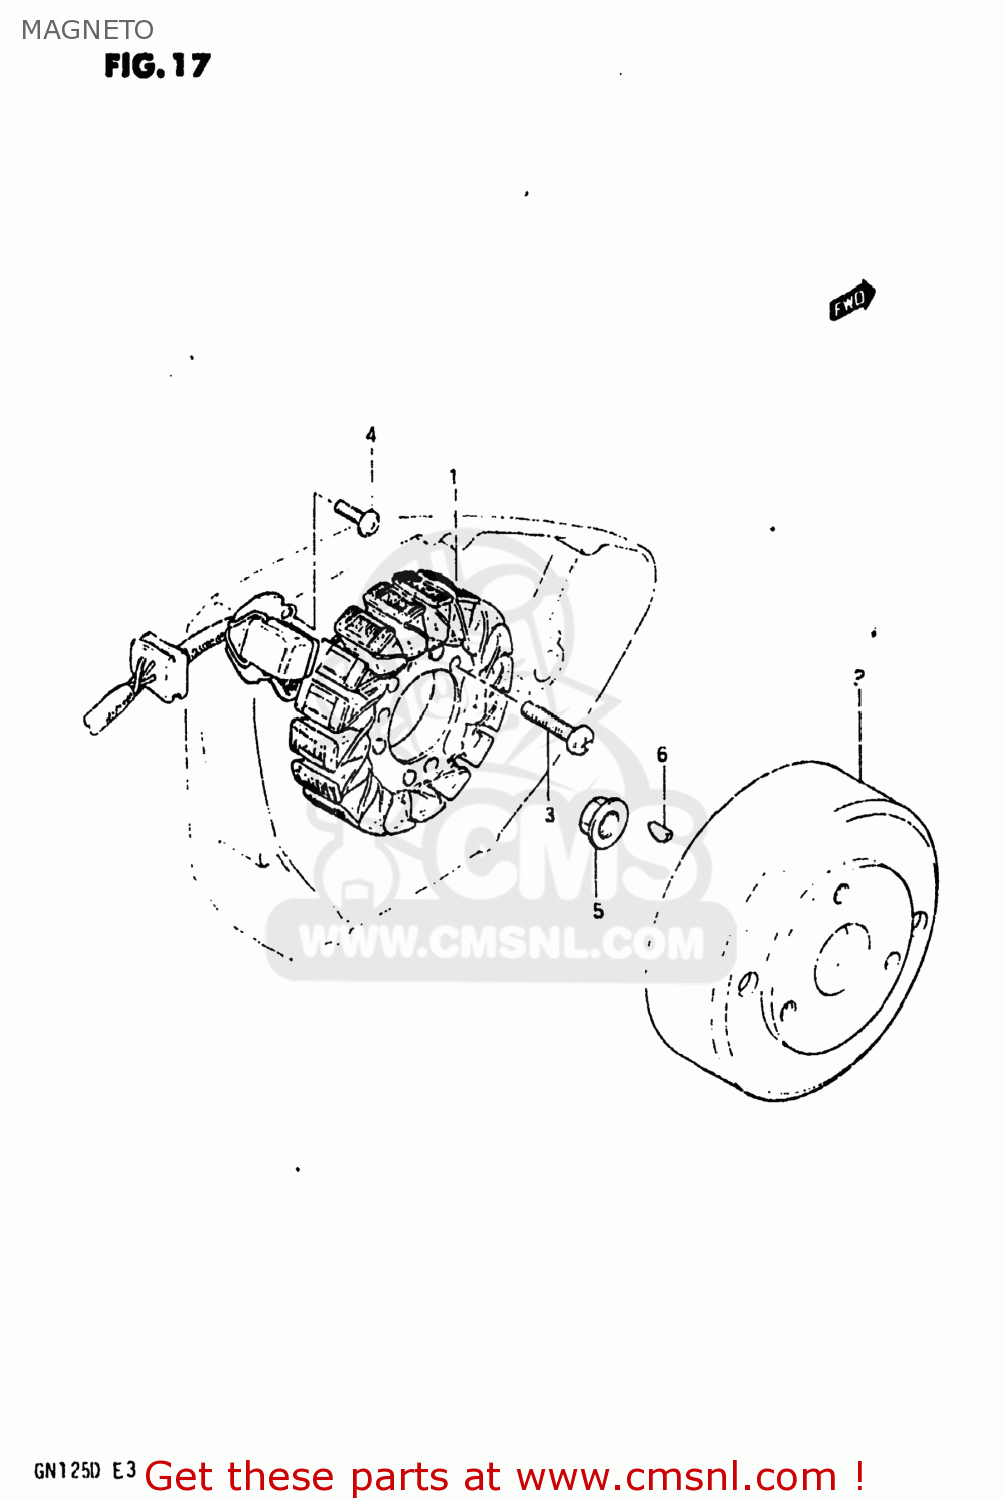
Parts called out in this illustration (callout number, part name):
1	STARTER ASSY
2	ROTOR,FLYWHEEL
3	SCREW
4	SCREW
5	NUT
6	KEY
